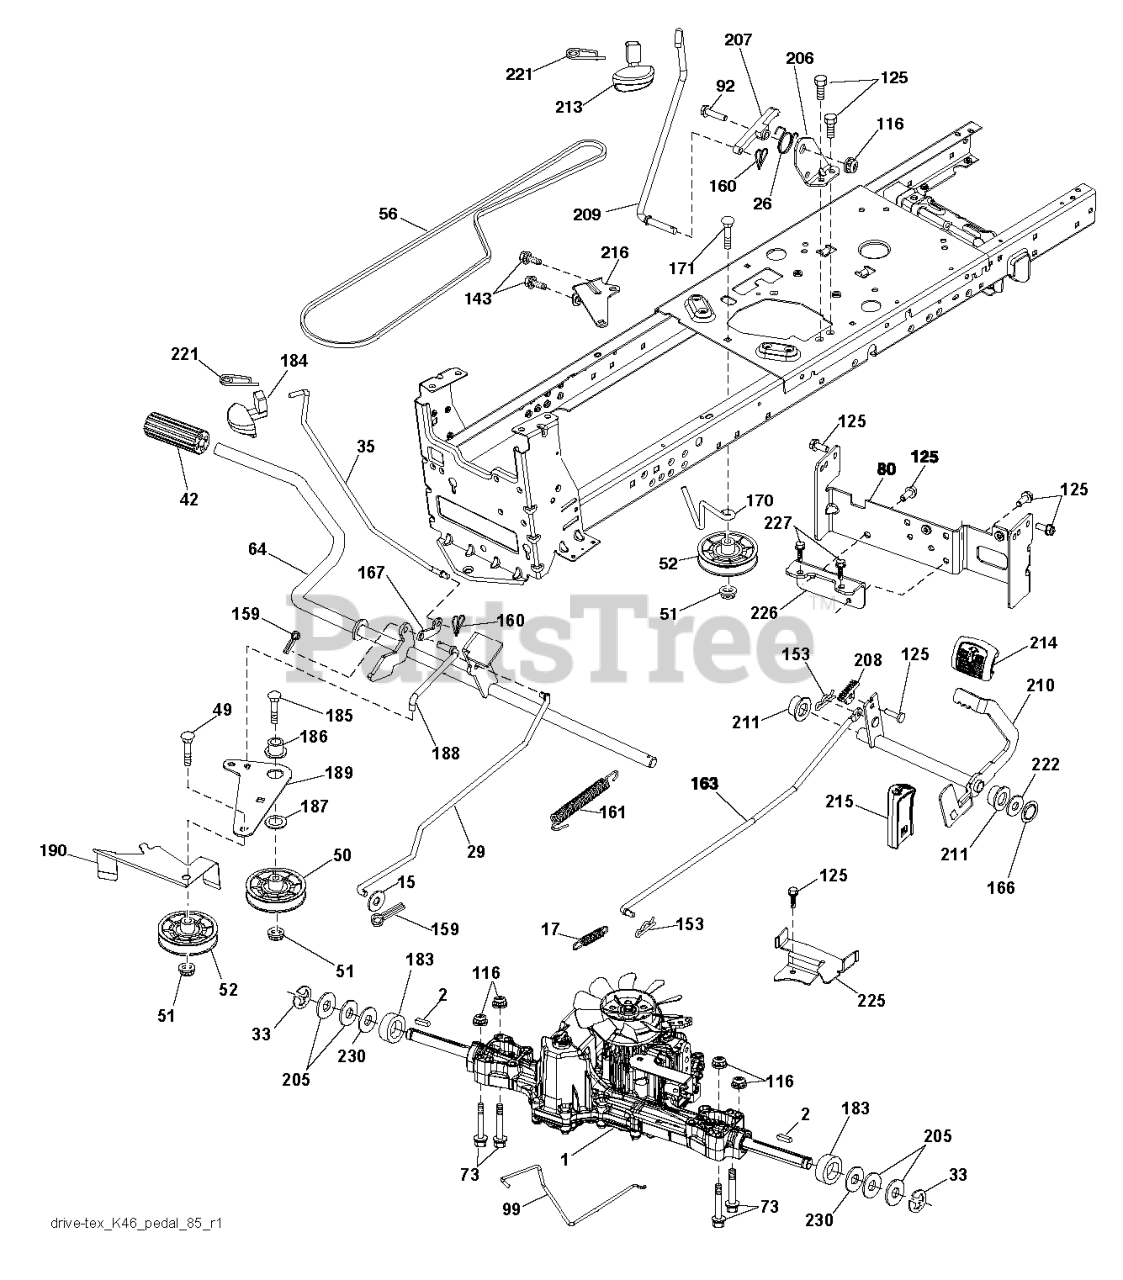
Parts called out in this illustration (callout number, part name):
2	SQUARE KEY
15	WASHER
17	SPRING.BRAKE.K46.GREEN
26	SPRING.RETURN.CRUISE
29	ROD.BRAKE.K46
35	ROD.BRAKE.PARTK.HUSQ.TEX
42	PEDAL COVER T
50	IDLER.FLAT.910.OFFSET
51	NUT LOCK FLG 3/8-16 UNC
52	IDLER.V-GROOVE.910.OFFSET
56	V-BELT.MOWER.92.40.42/K46
64	SHAFT.ASM.PEDAL.BRK.CNTR
73	BOLT
80	STRAP.TORQUE.K46.K57R.TT
92	BOLT
99	ROD.SPRING.BYPASS.K46.LT.Z
116	NUT LOCK HEX FLANGE 5/16-18
125	SCREW
143	SCREW LT
153	RETAINER M
159	COTTER PIN
160	RETAINER CLIP
161	SPRING, RETURN LT
163	ROD.CONTROL.K57R.K46
166	NUT.PUSH.625
167	LATCH.BRAKE.SPRING
170	KEEPER.V-IDLER.CENTER.
171	BOLT
183	SPACER AXLE
184	RB HANDLE.PARKG.BRK.HUS/PRED
186	SPACER.RETAINER
187	WASHER 12/32X2X10GA
188	RP.LINK.CLUTCH.GROUND.DRIVE
189	BELLCRANK.GROUND.DRIVE.TEX.
190	KEEPER.BELLCRANK.DRIVE
206	BRKT.MOUNT.LATCH.CRUIS
207	LATCH.CONTROL.CRUISE
208	GEAR.SECTOR.CONTROL.CR
209	ROD.CONTROL.CRUISE.GT.
210	ROCKER.ASM.PEDAL.CONTR
211	BEARING.NYLON
213	KNOB.CONTROL.CRUSIE.HU
214	PEDAL.FORWARD.PAD.TEX
215	PEDAL.REVERSE.TEX.GT.4
216	BRACKET.PULLEY.IDLER.W/TEX
221	RETAINER.SPRING.CLIP.H
222	WASHER 21/32 X 1-1/4 X 10 GA.
225	KEEPER.BELT.TRANSAXLE.K46
226	BRACKET.MOUNT.TORQUE.K46.TLT
227	SCREW.THDROL.5/16-18X3/4.TTY
230	WASHER.HARDENED
